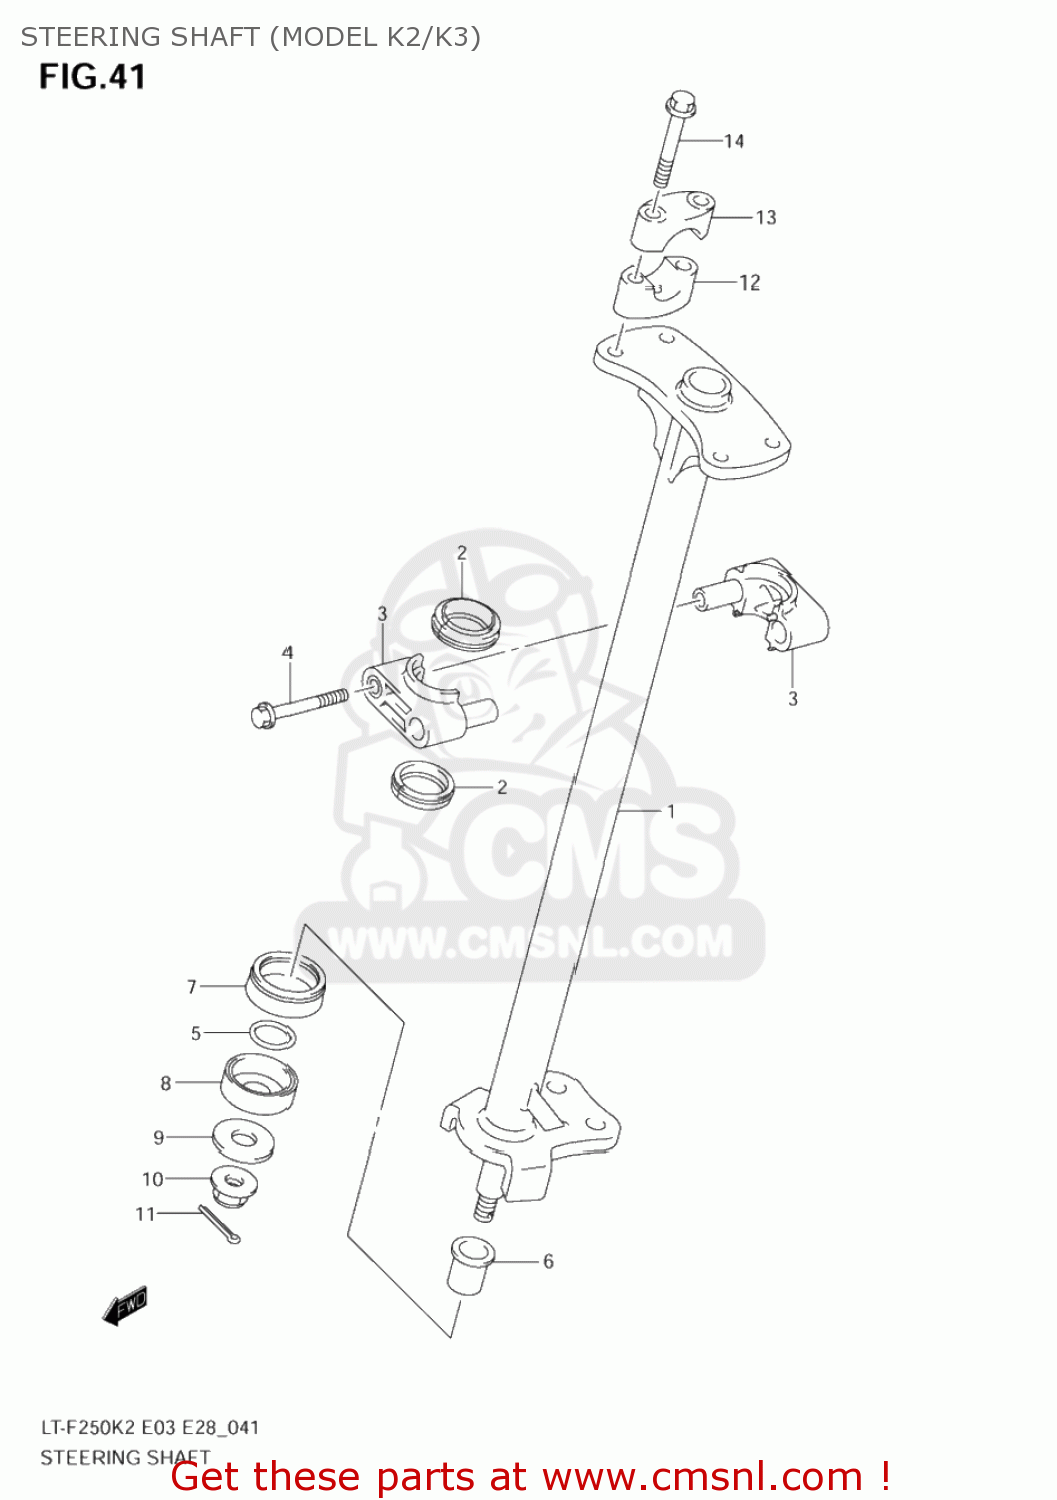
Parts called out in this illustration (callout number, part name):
1	SHAFT,STEERING
2	SEAL,STEERING SHAFT HLDR DUST
3	HOLDER,STEERING SHAFT
4	BOLT
5	O RING(D:3.1,ID:16.8)
6	BUSH
7	DUST SEAL,STEERING SHAFT
8	SEAL,STEERING DUST,LOWER
9	WASHER(12.5X32X2.3)
10	NUT
11	PIN 20X20
12	HOLDER,HANDLE LWR
13	HOLDER,HANDLE UPR
14	BOLT
